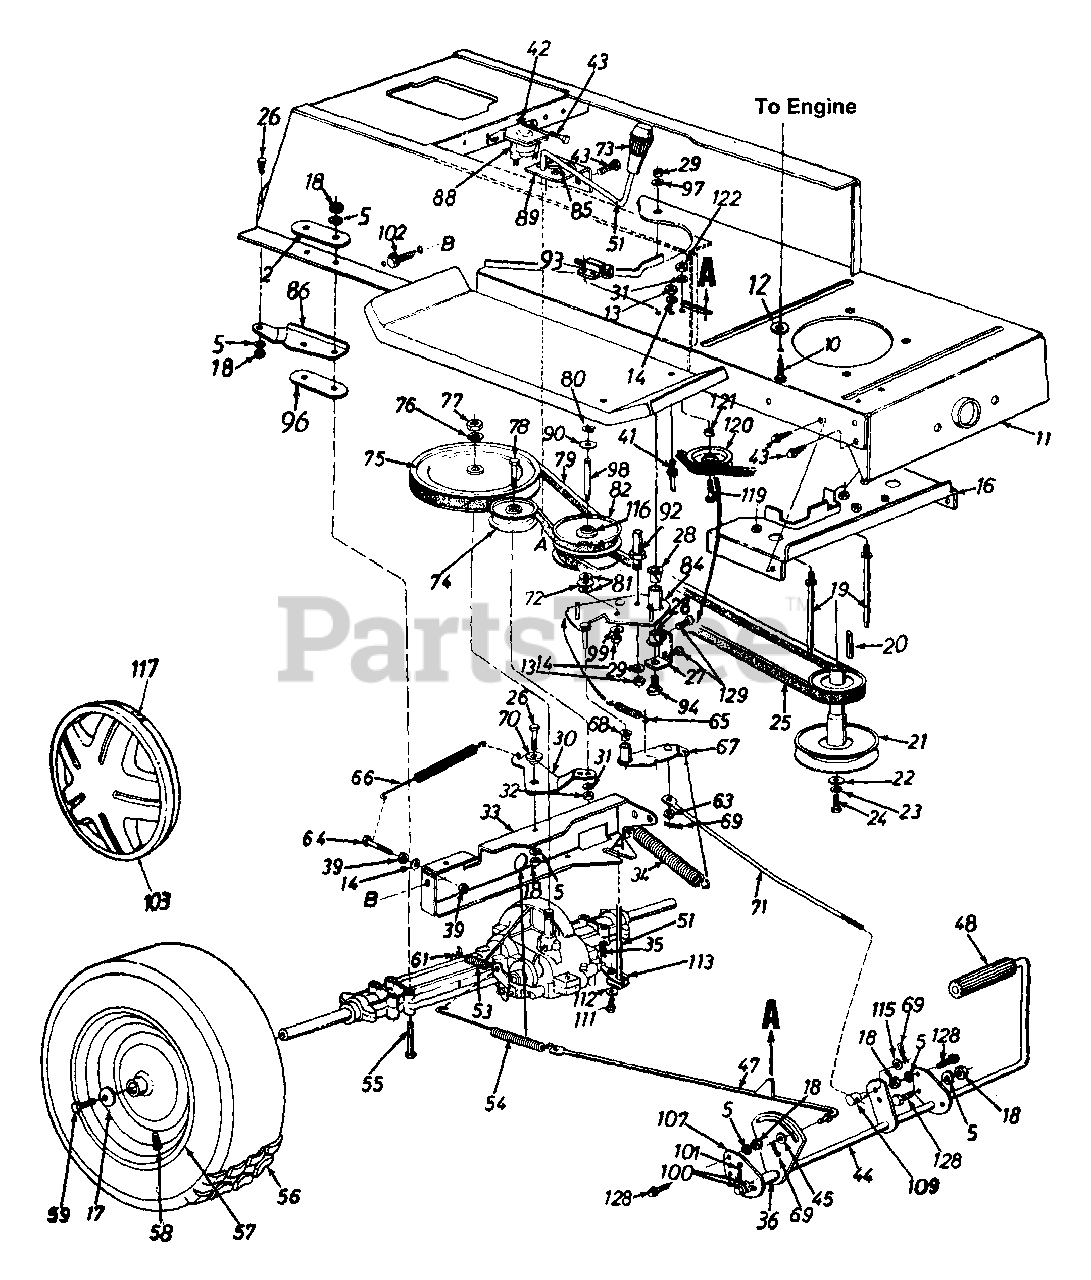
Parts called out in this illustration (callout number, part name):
5	L-Wash. 5/16" I.D.
10	Hex L-Wash. Tap Scr. 3/8-16 x 1.5" Lg.
13	Hex Nut 1/4-20 Thd.
14	L-Wash. 1/4" I.D.
18	Hex Nut 5/16-18 Thd.
19	Belt Guard Stud 3.6" Lg.
20	Sq. Key 1/4" x 1/4" x 2.00"
21	Engine Pulley
22	Fl-Wash. 7/16" I.D. x 1.25"
23	L-Wash. 7/16" I.D.
24	Hex Bolt 7/16-20 x 1.50" Lg.
25	Variable-Speed Belt
26	Hex Bolt 5/16-18 x .75" Lg.
27	Bearing Shaft Bracket Ass'y.
28	Flanged Nyliner Brg. 5/8" I.D. x .88" Lg.
29	Hex Nut 3/8-24 Thd.
31	L-Wash. 3/8" I.D.
32	Hex Nut 3/8-24 Thd.
35	Inter. Cotter Pin
36	Spacer .63" I.D.
39	Hex Nut 1/4-28 Thd.
41	Belt Guard Pin
42	Ext. L-Wash. 1/4" I.D.
43	Hex Wash. Hd. S-Tap Scr. 1/4-20 x .50" Lg.
47	Brake Rod Ass'y.
48	Foot Pad
51	Shift Lever Ass'y.
53	Ext. Spring .38" O.D. x 2.5"
54	Ext. Spring .59" O.D. x 7.08"
55	Hex Bolt 5/16-18 x 3" Lg.
58	Air Valve
59	Hex Bolt 5/16-24 x .75" Lg.
61	Brake Return Spring Anchor
63	Fl-Wash. .34" I.D. x .68" O.D.
64	Hex Bolt 1/4-28 x 1.25" Lg.
65	Ext. Spring
66	Ext. Spring .62" O.D. x 6.12"
68	Flanged Bearing
69	Cotter Pin 3/32" Dia.
70	Shoulder Spacer .27" Lg.
71	Speed Control Link
72	Truss Bearing .56 Dia. x 1.25"
73	Shift Knob
74	Fl-Idler Pulley 3.25" x .75"
76	Bell-Wash. .56" I.D. x 1.125"
77	Hex Jam Nut 5/16-18 Thd.
78	Hex Bolt 3/8-24 x 1.75" Lg.
79	Variable Speed Belt
80	Snap Ring .56" Dia.
82	Variable Speed Pulley Ass'y. 5" O.D.
90	Teflon Washer .565" I.D.
92	Belt Keeper 3" Lg.
93	Safety Switch (Clutch)
94	Shld. Bolt 3/8-24 x 3.12" Lg.
96	Transaxle Spacer
97	Bell-Wash. .38" I.D. x .88"
98	Shaft .56" Dia. x 3.875" Lg.
99	Bell-Wash. .39" I.D. x 1.12"
100	Fl-Wash. .64" I.D. x .94"
101	Cotter Pin 1/8" Dia. x 1.25"
102	Hex Wash. Hd. Scr. 5/16-18 x .62" Lg.
111	Hex Bolt 1/4-28 x .50" Lg.
112	Bell-Wash. .265" I.D. x .75"
113	Shift Lever Link Ass'y.
115	Fl-Wash. .385" I.D. x .62"
116	Needle Brgs.
117	Spring Clip
119	Hex Bolt 3/8-16 x 1.25" Lg.
120	Fl-Idler w/Flanges 2.75" O.D.
121	Fl-Wash. .39" I.D. x 1.12" O.D.
122	Hex Nut 3/8-16 Thd.
128	Hex Wash. TT-Tap Scr. 5/16-18 x .75" Lg.
129	Hex Wash. AB-Tap Scr. 5/16-18 x .75" Lg.
